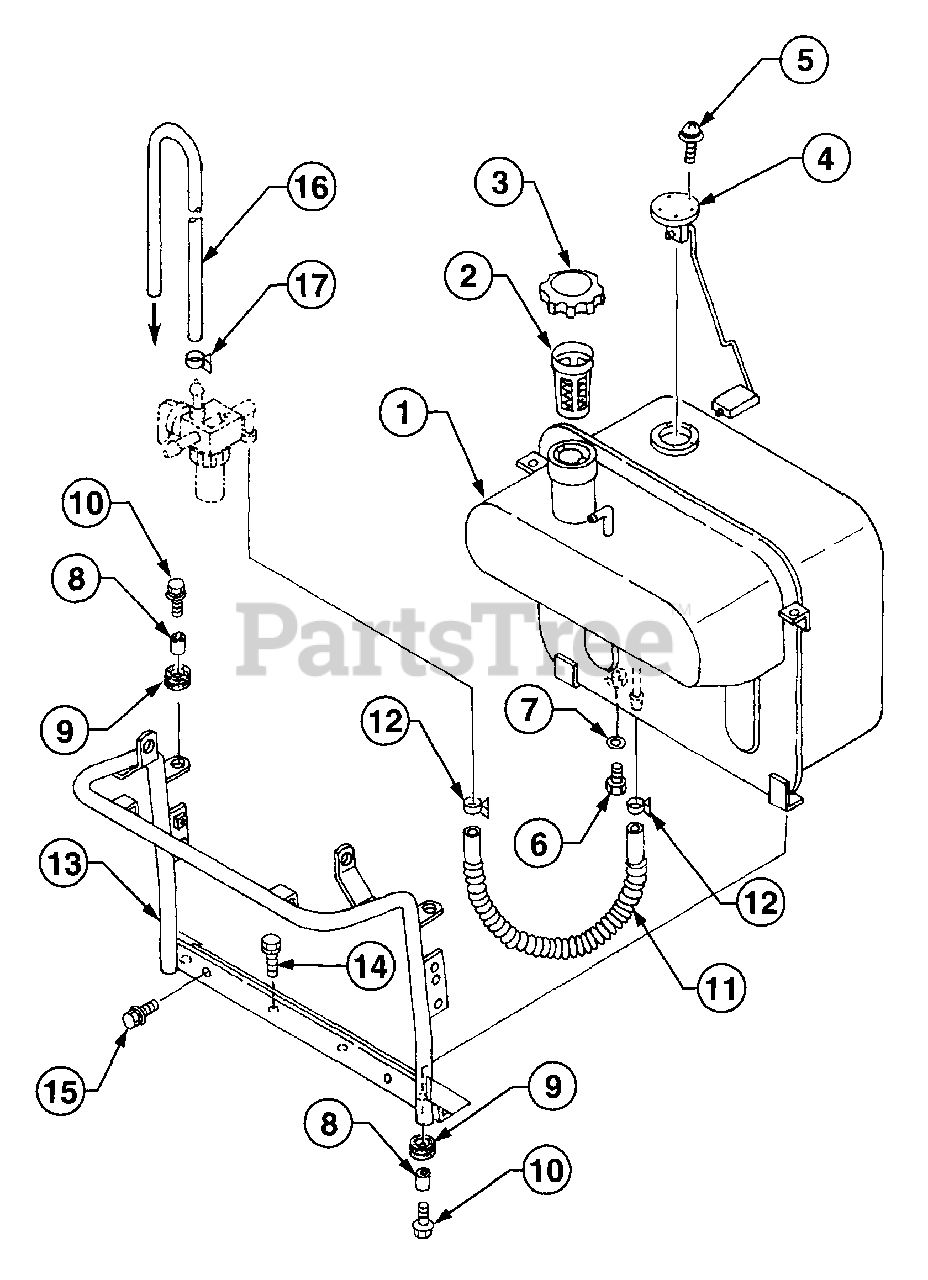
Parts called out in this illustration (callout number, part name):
5	Screw, w/Washer
10	Bolt, w/Washer
13	Bracket, Tank
14	Bolt, w/Washer
15	Bolt, w/Washer
